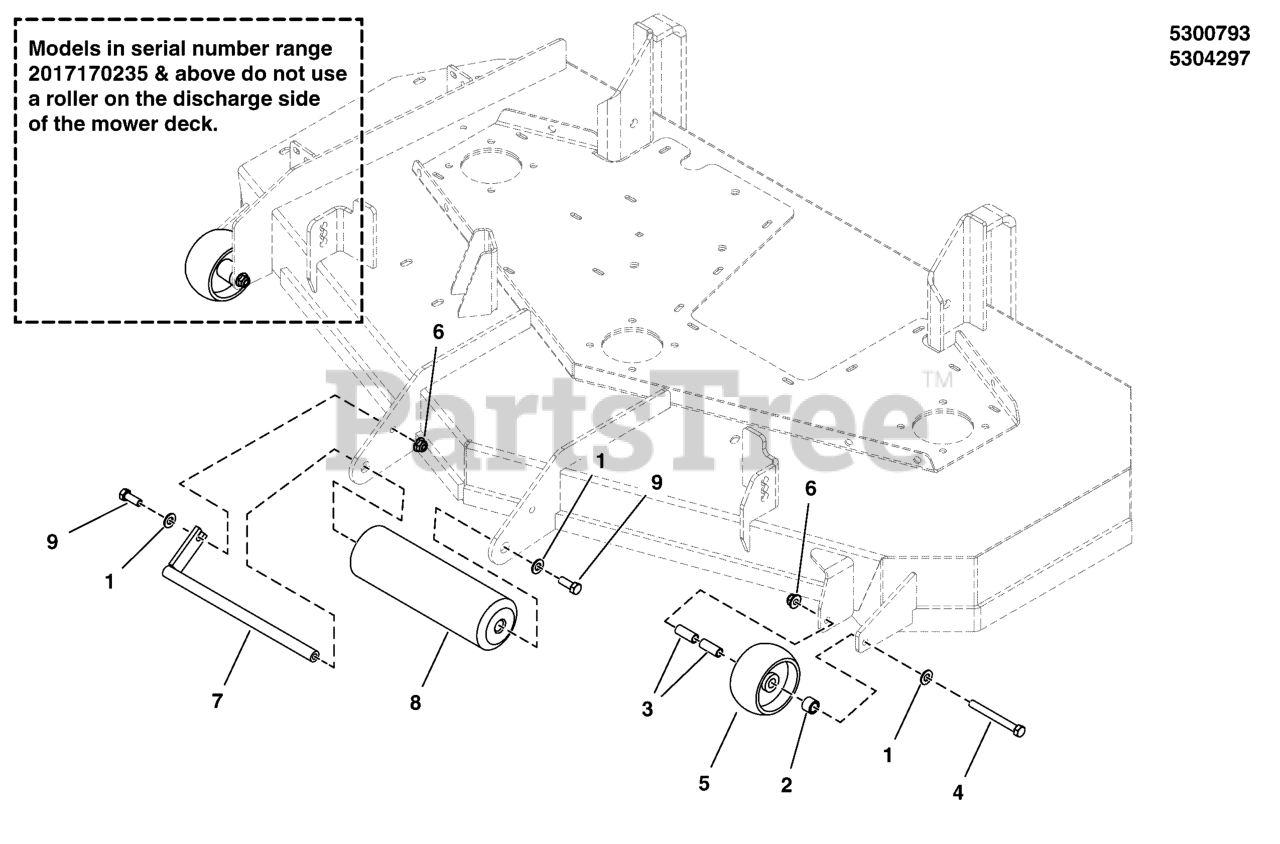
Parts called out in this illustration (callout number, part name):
1	WASHER, 3/8 SAE
2	SPACER, .51 X .75 X .56, CZ
3	SPACER, .38 X .50 X 1.25, CZ
4	BOLT, 3/8-16 X 3-1/2" GD5 CZ
5	WHEEL- 2.00 WIDE 3.88 DIA 0.531ID POLY
6	NUT, 3/8-16 HEX NYLOCK FLANGE
8	ROLLER, DECK
9	BOLT, 3/8-16 X 1" GD5 CZ
